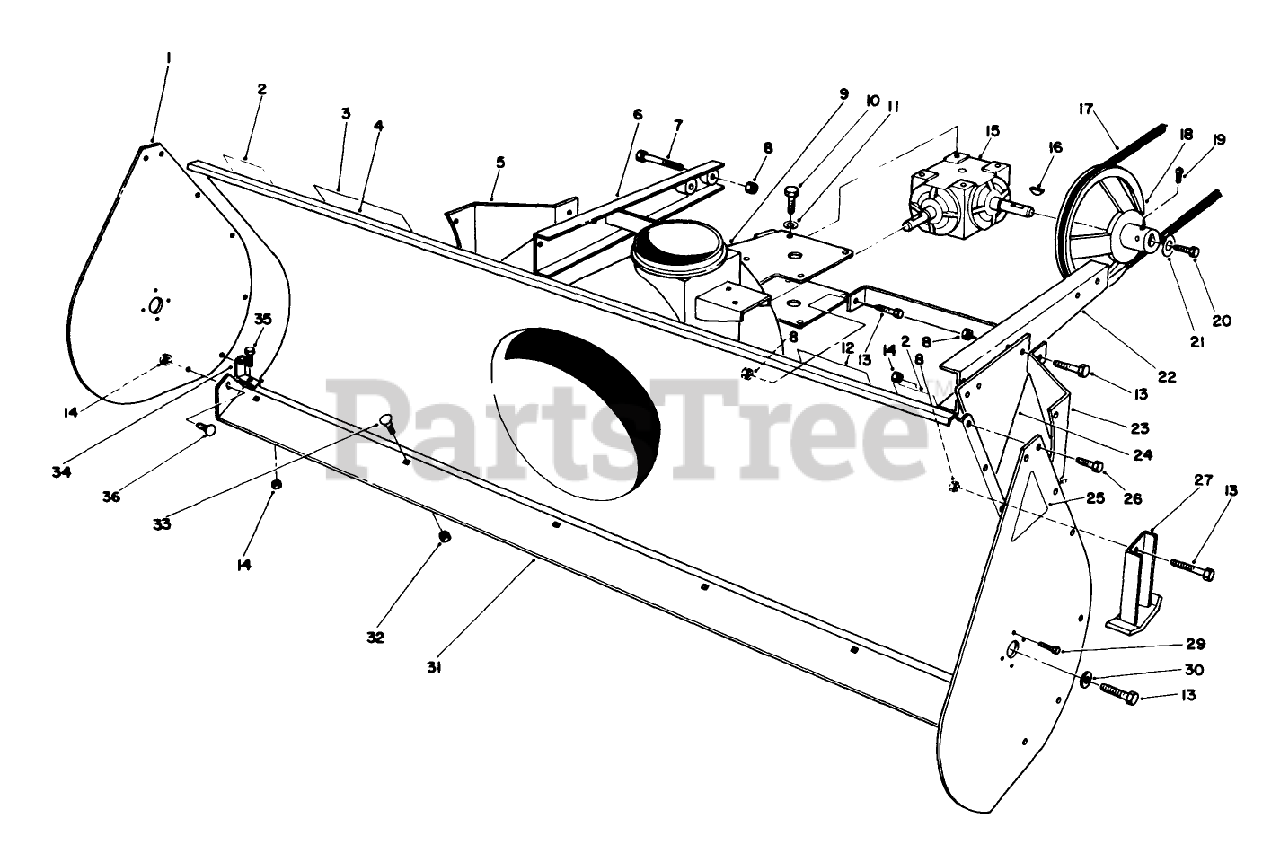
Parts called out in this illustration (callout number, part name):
1	Plate-Side
2	DECAL-WARNING, AUGER
3	Decal-Warning
4	HOUSING WA R
5	RH EXTENSION PLT R
6	RH EXT BAR WA R
7	SCREW-HH
8	NUT-LOCK, NI
9	CHUTE RING
10	SCREW-HH
11	WASHER-LOCK, INTERNAL
12	Decal-Rear Weight
13	SCREW-HH
14	NUT-LOCK, NI
15	GEARBOX
16	KEY-WOODRUFF
17	V-BELT
18	DRIVE PULLEY
19	SCREW-SET, SQH
20	BOLT 60183
21	WASHER-FLAT
22	LH EXT BAR WA R
23	LH EXTENSION PLT R
24	SKID MTG PLT R
25	AUGER SIDE PLT DECAL
26	SCREW-HH
27	SKID WA R
29	SCREW-HH
30	WASHER
31	Blade-Scraper
32	NUT-LOCK, NI
33	SCREW-CARR
34	BLADE SUPPORT BRKT R
35	SCREW-HH
